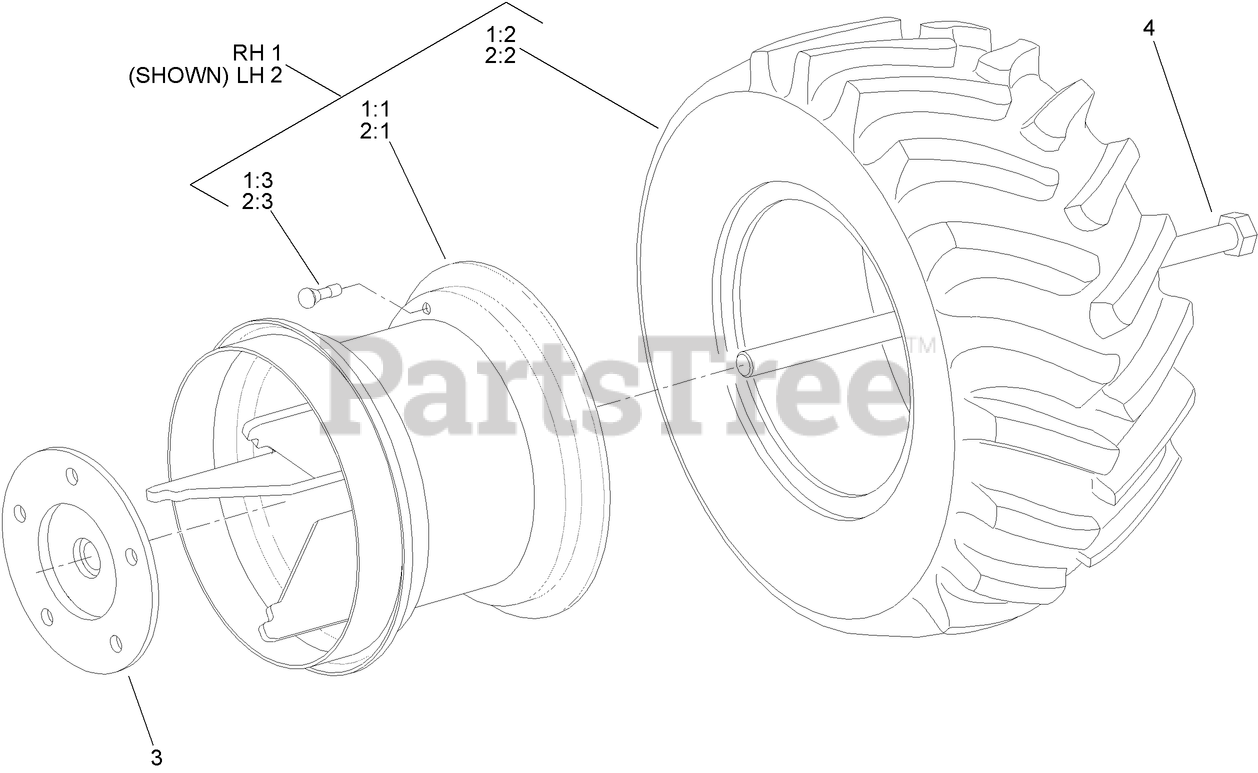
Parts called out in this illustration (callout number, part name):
1	RH DUAL 23 INCH WHEEL ASM
1:1	WHEEL-DUAL
1:3	STEM-VALVE
2	LH DUAL 23 INCH WHEEL ASM
2:1	WHEEL-DUAL
2:3	STEM-VALVE
3	PLATE-RETAINER
4	SCREW-HH
